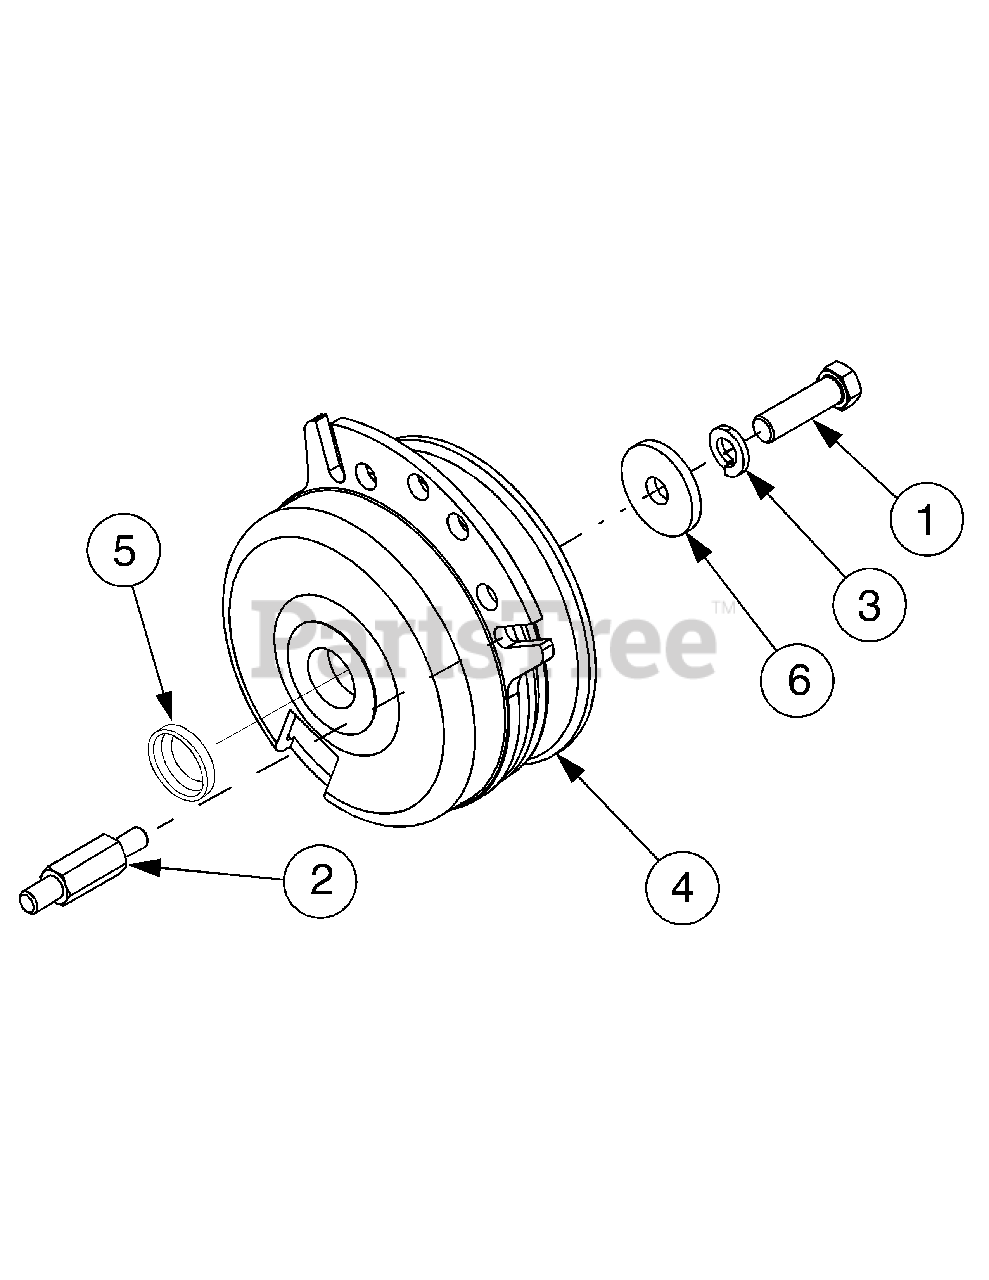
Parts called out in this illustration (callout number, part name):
1	Screw, Hex Cap, 7/16-20 x 1.5 GR5
2	Stud, Clutch Stop
3	Washer, Lock, 3/8
4	Clutch Assy, PTO
5	Spacer, 1.0 x 1.62 x .21
5	Spacer, 1.13 x 1.62 x .21
6	Washer, Flat, .445 x 1.5 x 1.72 Hdn
